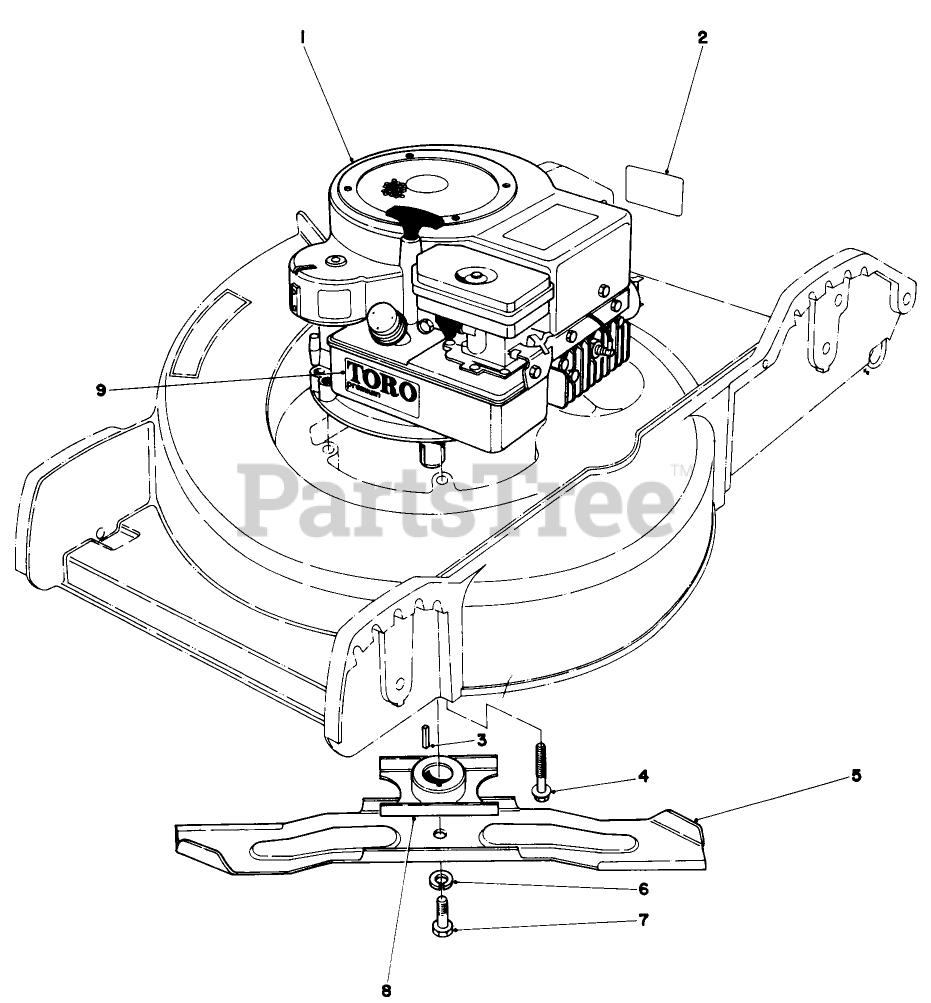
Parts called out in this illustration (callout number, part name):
1	Engine
2	Decal Maintenance
3	KEY-SQUARE
4	3/8-16 X 2 CAPSCREW
5	Blade
6	WASHER-LOCK
7	SPECIAL SCREW
8	Blade Retailer
9	Decal
